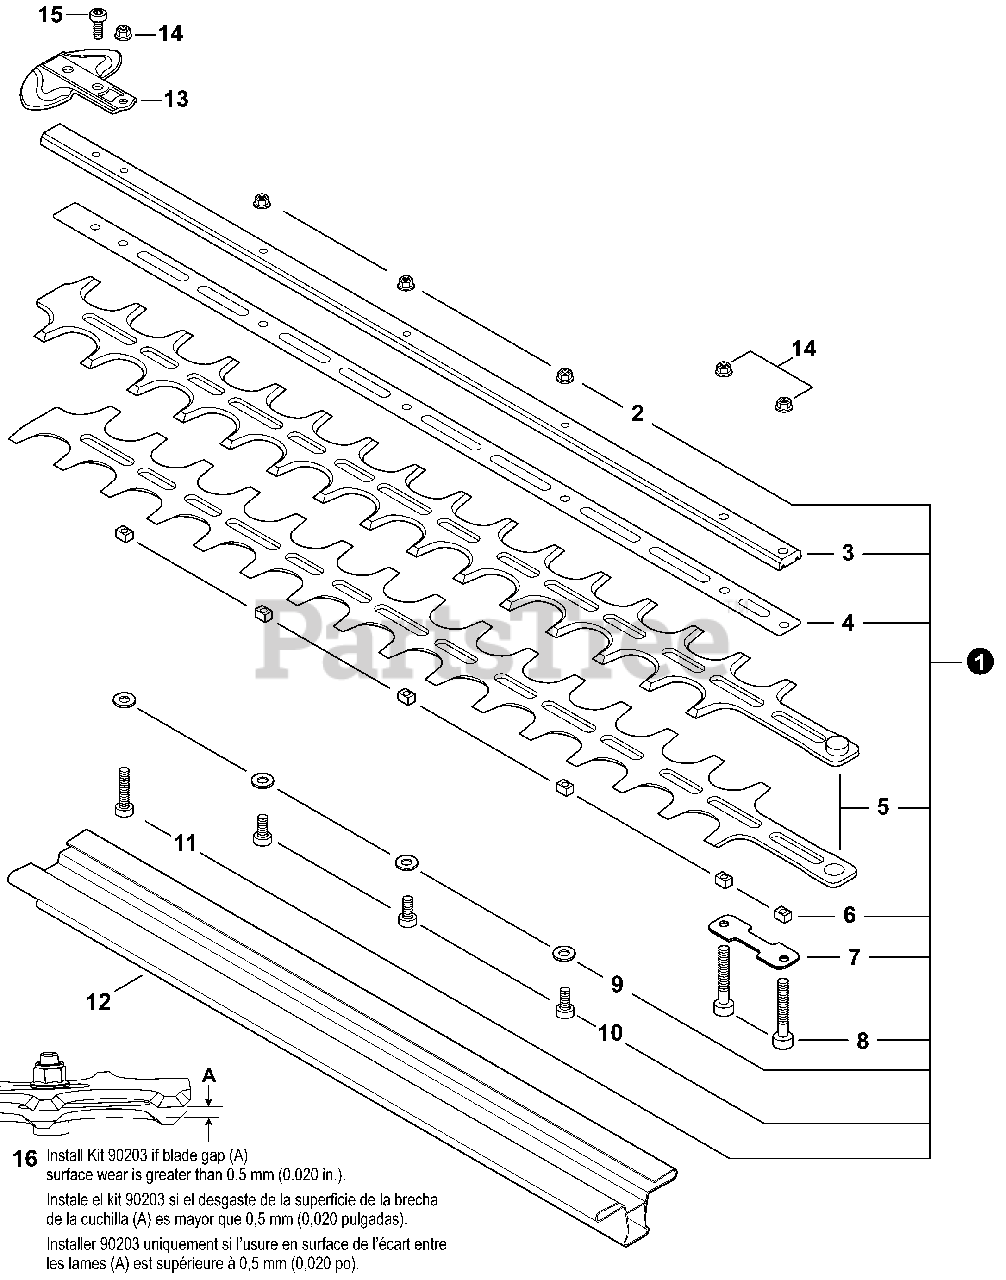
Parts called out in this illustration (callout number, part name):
1	CUTTER ASSY, 20"
2	NUT, FLANGE M5
3	SUPPORT, CUTTER 20"
4	PLATE, CUTTER 20"
5	CUTTER, 20"
6	GUIDE, BLADE 5
7	PLATE, EYE
8	BOLT, TORX 5×30
10	BOLT, TORX 5×20
11	BOLT, TORX 5×25
12	SCABBARD
13	GUARD, TIP
14	NUT, FLANGE M5
15	BOLT, TORX 5×8
16	BLADE KIT, ADJUSTABLE
